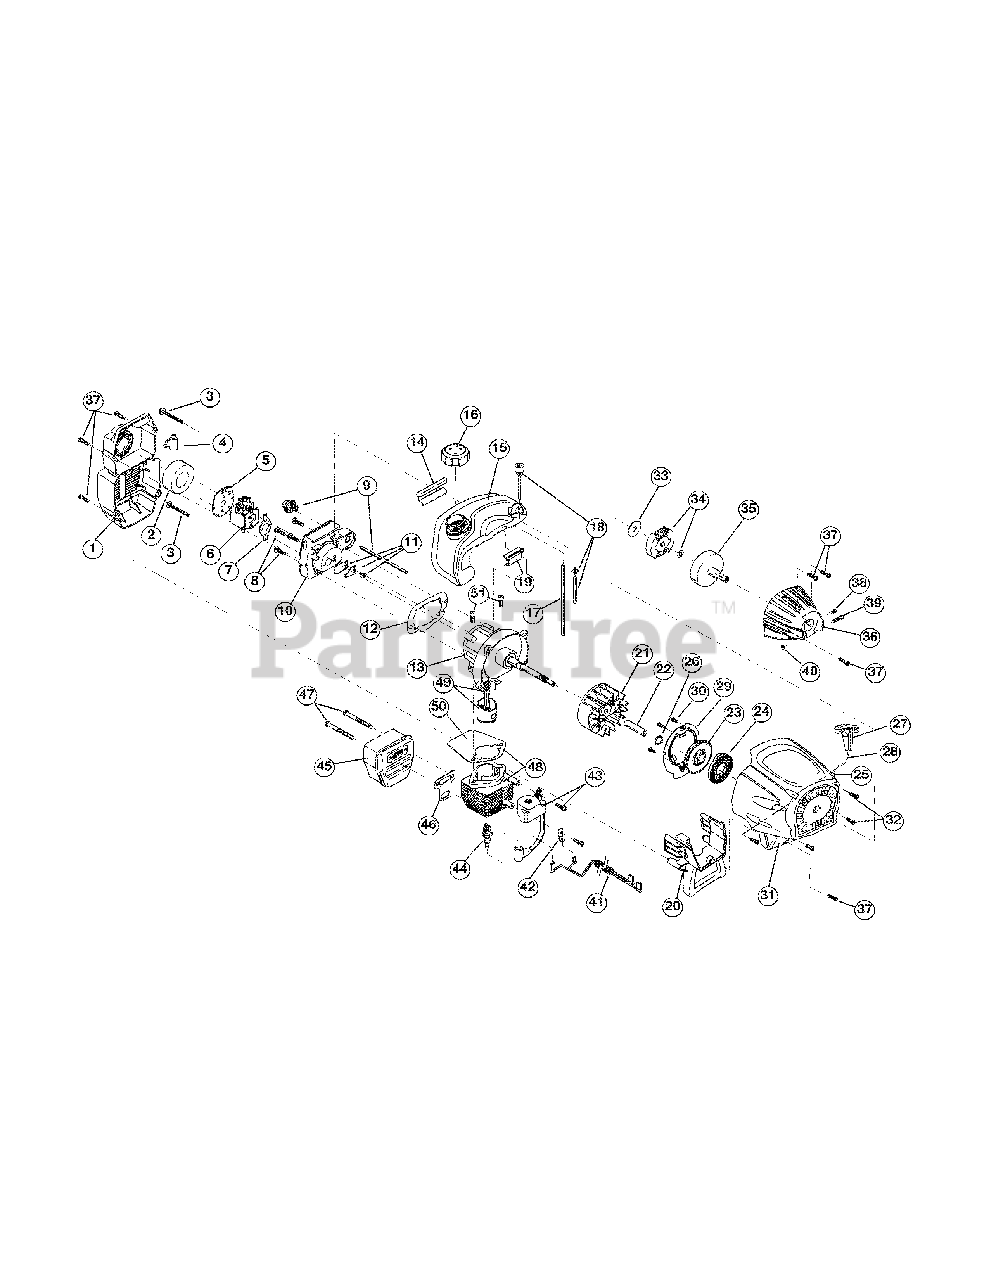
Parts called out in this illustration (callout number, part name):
1	Air Cleaner Cover Assembly (includes 2 & 37)
2	Air Cleaner Filter
3	Carburetor Mounting Screw Assembly
4	Choke Extension
5	Choke Plate
6	Carburetor Assembly (includes 7 & 18)
7	Carburetor Gasket
8	Carb Mount Screw
9	Primer & Hose Assembly
10	Carb Mount Assembly (includes 8, 11 & 12)
11	Reed Assembly
12	Carburetor Mount Gasket
13	Crankcase Service Assembly (includes 8)
14	Rear Mounting Pad
15	Fuel Tank Assembly (includes 16-18)
16	Fuel Cap Assembly
17	Fuel Return Line
18	Fuel Line Assembly
19	Front Mounting Pad
20	Shroud Extension & Stand (includes 37)
21	Flywheel Assembly
23	Recoil Pulley Assembly
24	Recoil Spring
25	Rope Guide
26	Pulley Retainer
27	Pull Handle
29	Pressure Plate Assembly
30	Plate Screw
31	Starter Housing Assembly (includes 23-30, 32 & 37)
32	Housing Screw
33	Clutch Washer
34	Clutch Rotor Assembly
35	Clutch Drum Assembly
36	Clutch Cover Assembly (includes 37-40)
37	Cover Screw
38	Anti-Rotation Screw
39	Clamping Screw
40	Clamping Nut
41	Wire Leads and Sleeve
42	Ground Tab
43	Module Assembly
45	Muffler Assembly (includes 46-47)
45	Muffler Assembly (includes 46-47 and Spark Arrestor)
46	Exhaust Gasket
47	Muffler Mounting Bolts
48	Cylinder Assembly (includes 50 & 51)
49	Piston and Rod Assembly
50	Cylinder Gasket
51	Cylinder Bolt
